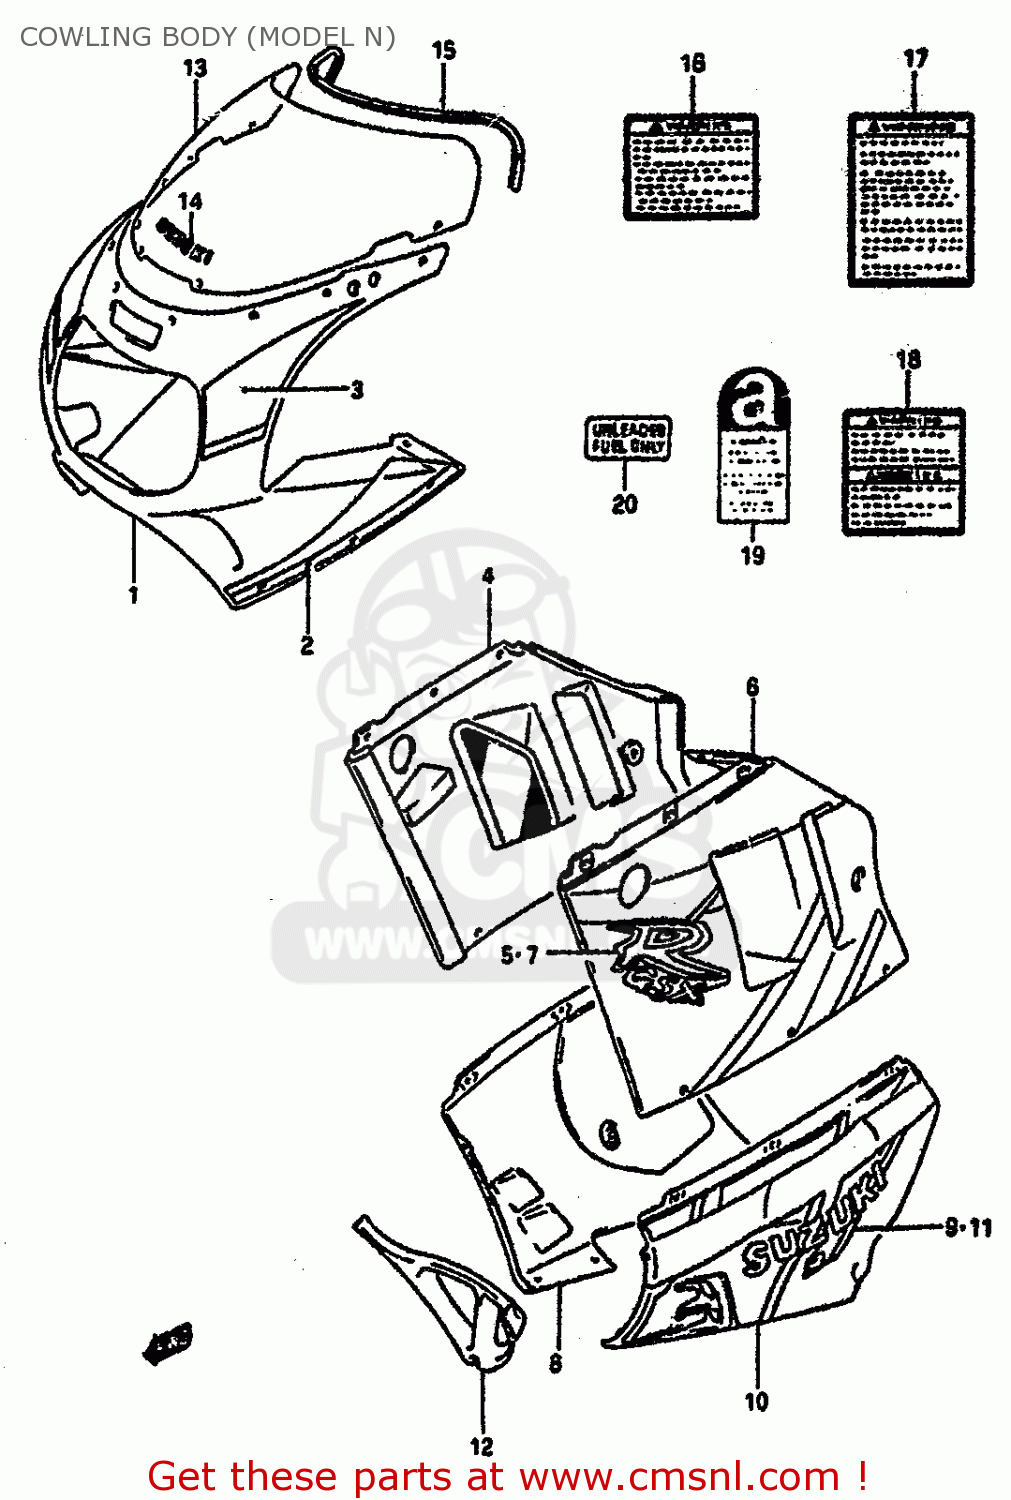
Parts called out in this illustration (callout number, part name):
1	BODY ASSY,COWLING
2	TAPE SET,COWLING,UPPER SIDE
3	TAPE SET,COWL UPR FR
4	COVER,COWLING SIDE,R
5	TAPE SET,COWLING SIDE
6	COVER COMP,COWLING SIDE,LEFT
7	TAPE SET,COWL SIDE,L
8	COWLING,UNDER,R(WHITE)
9	TAPE,COWL UNDER STRIPE,R
10	COWLING,UNDER,L(WHITE)
11	TAPE,COWL UNDER STRIPE,L
12	COWLING,UNDER,CENTER (W
13	SCREEN SET,WIND
14	EMBLEM,WINDSCREEN
15	MOLD,COWLING
16	LABEL, WARNING SAFETY
17	LABEL (WARNING SCREEN)
18	LABEL (WARNING)
19	LABEL,ASBESTOS WARNING
20	LABEL,CAUTION
